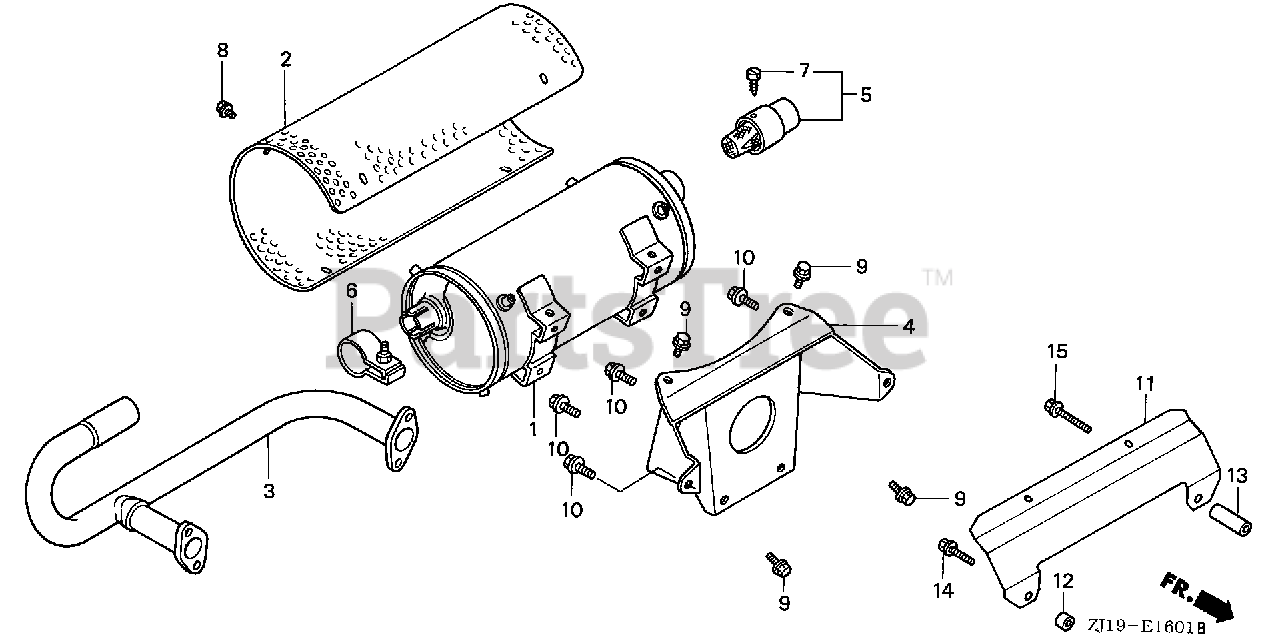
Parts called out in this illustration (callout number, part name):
1	MUFFLER COMP. (HIGH)
2	PROTECTOR, MUFFLER (HIGH)
3	PIPE COMP., EX. (HIGH-L)
4	STAY, MUFFLER (HIGH)
5	ARRESTER, SPARK
6	BAND ASSY.
7	SCREW (NELSON)
8	BOLT, FLANGE (6X8)
9	BOLT, FLANGE (8X14)
10	BOLT, FLANGE (8X20)
